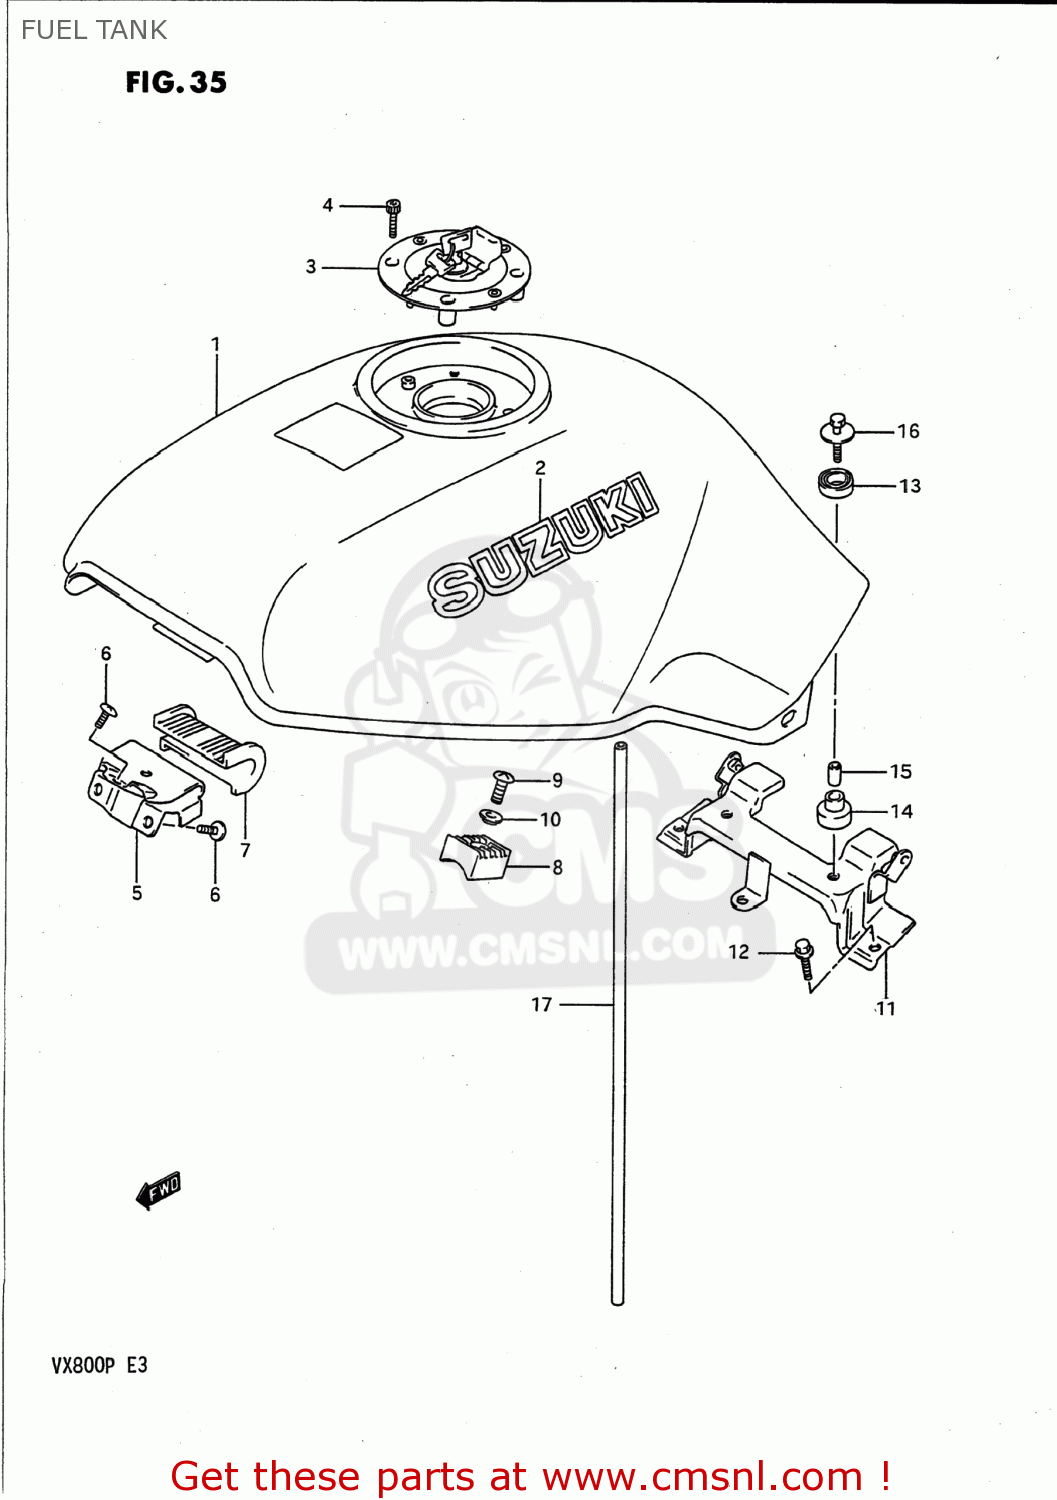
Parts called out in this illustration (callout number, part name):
1	TANK ASSEMBLY,FUEL
2	EMBLEM
3	CAP SET,FUEL TANK
4	BOLT(5X20)
5	BRACKET,FUEL TANK FR
6	SCREW
7	CUSHION,FUEL TANK,FRONT
8	CUSHION,FUEL TANK
9	SCREW
10	WASHER
11	BRACKET,FUEL TANK
12	BOLT 6X16
13	CUSHION
14	CUSHION
15	SPACER
16	BOLT
17	HOSE(5X8.2X600)
